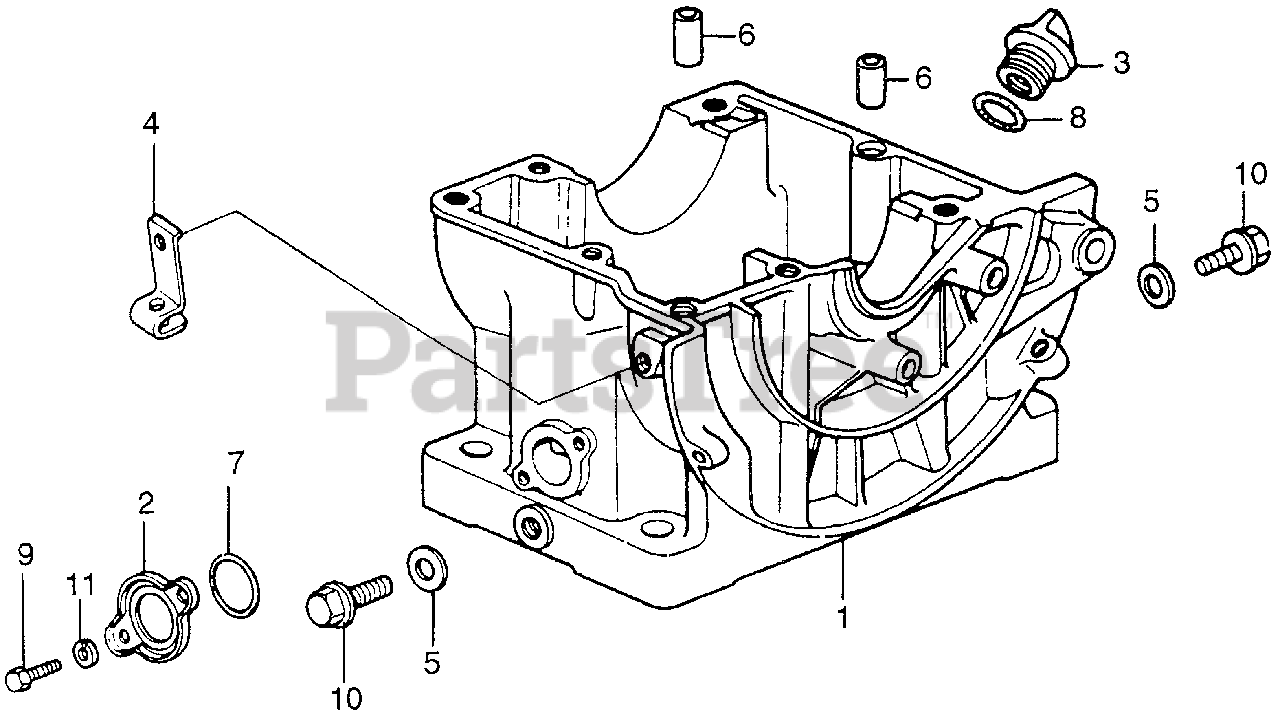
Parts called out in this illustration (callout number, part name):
1	PAN, OIL (NOT AVAILABLE)
2	COVER, OIL PAN
4	HOLDER, CABLE (NOT AVAILABLE)
5	WASHER, DRAIN PLUG (12MM)
6	PIN, KNOCK (8.5X11) (NOT AVAILABLE)
7	O-RING (27X2.0)
8	O-RING (26X2.7)
9	BOLT, HEX. (6X12)
10	BOLT, DRAIN PLUG (12MM)
